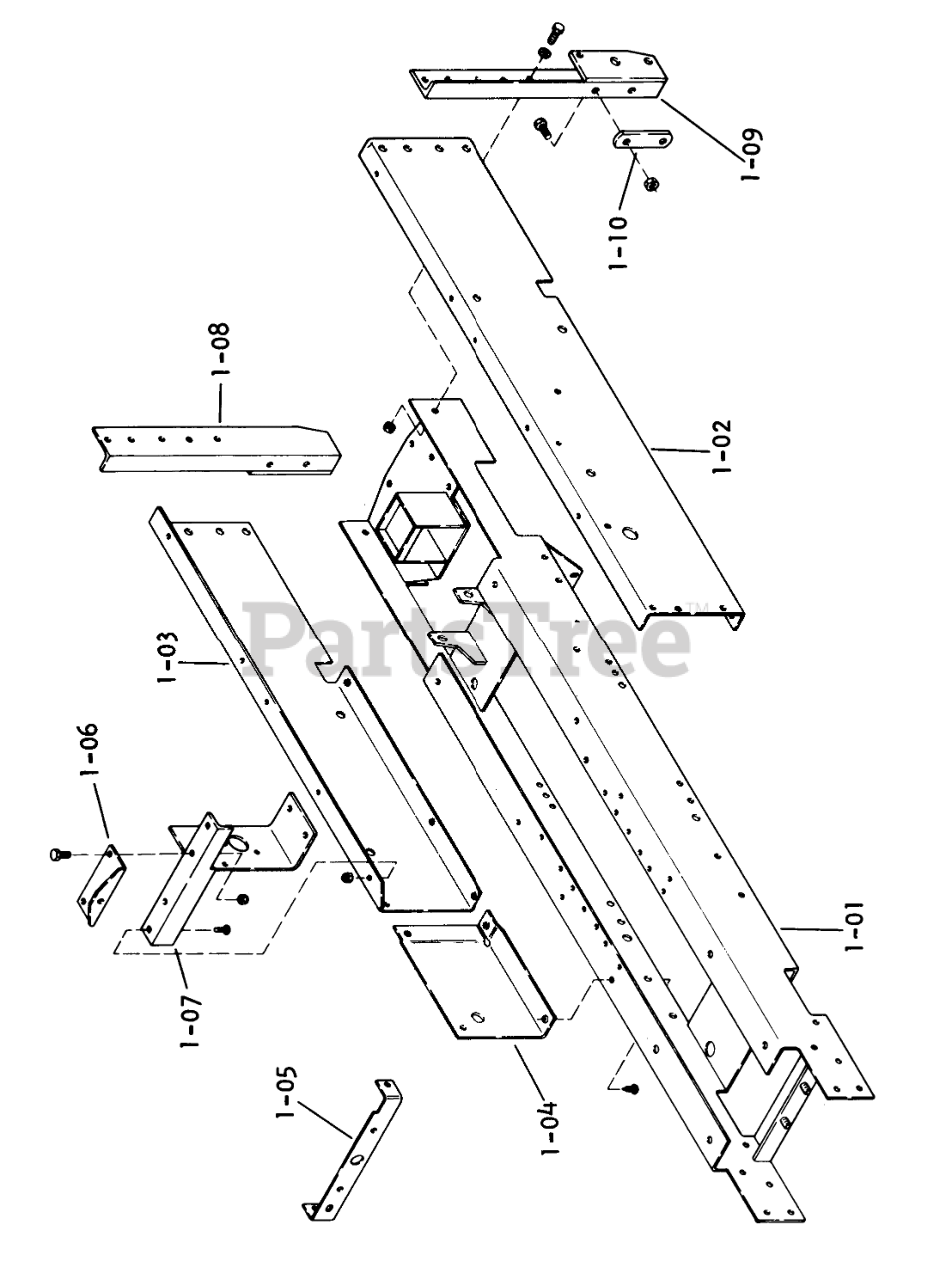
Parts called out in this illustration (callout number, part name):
1-01	Frame Assy.
1-02	Side Panel, L.H.
1-03	Hex Nut
1-04	Access Plate
1-05	Pump Mounting Plate
1-06	Pump Hanger Bracket
1-07	Steering Gear Support
1-08	Assy-Angle RH
1-09	Assy-Angle LH
1-10	BRACKET-REAR LINK MOUNTING
